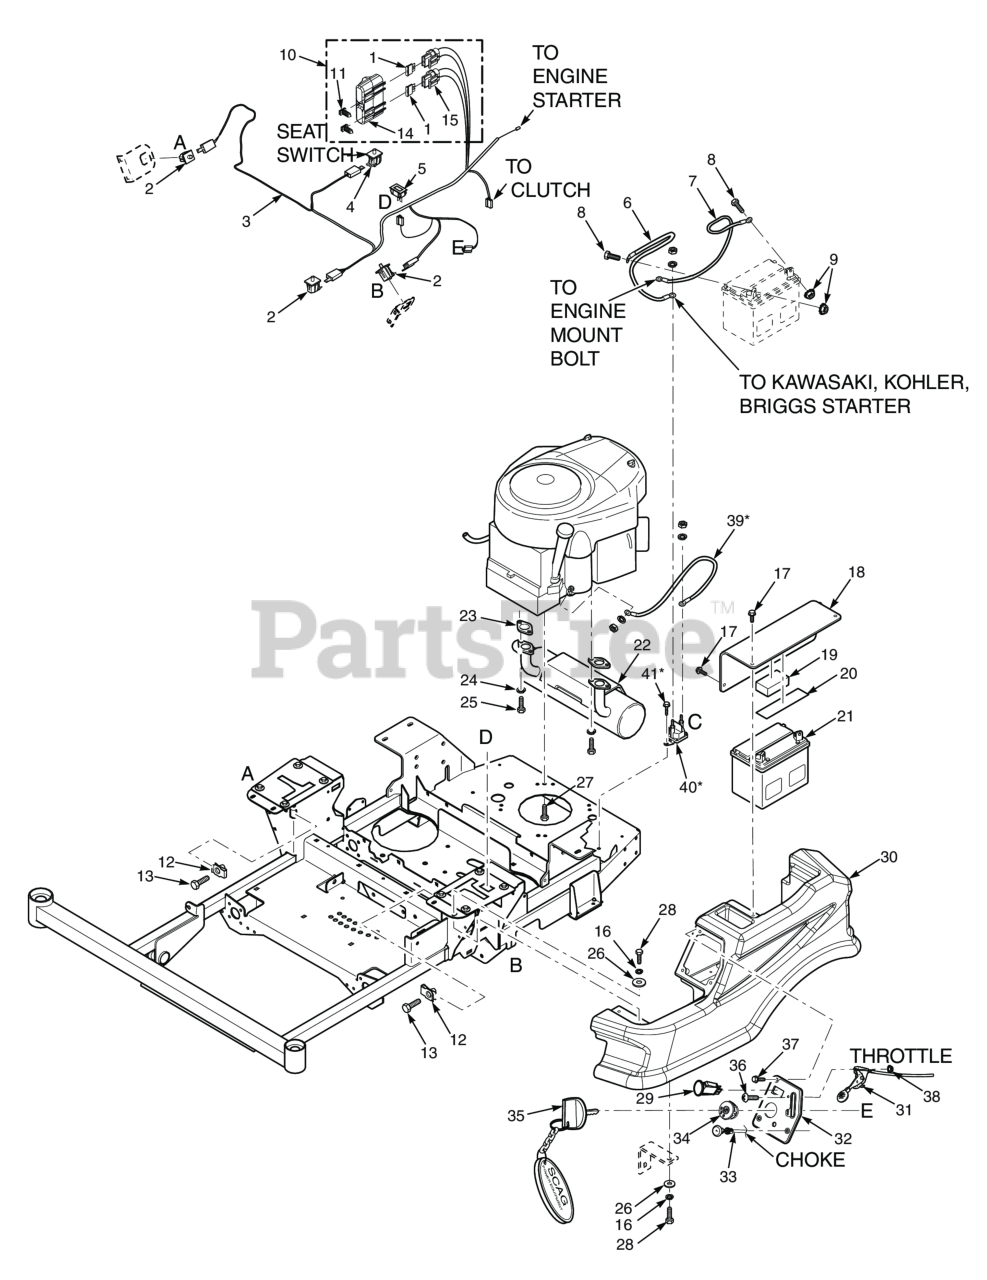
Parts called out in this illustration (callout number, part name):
1	FUSE, 20 AMP BLADE TYPE AUTOMOTIVE
2	Switch, Double Pole - Plunger
3	Wire Harness, Main
4	Switch, Double Pole - Twist
5	Hour Meter, Inductive
6	Battery Cable, 25" Red (Kawasaki)
7	Battery Cable, 27" Black (35BV & 37BV-EFI) - Briggs & Stratton
8	Bolt, Hex Head 1/4-20 x .5" Battery, (Not Available Through Scag)
9	Nut, 1/4 - 20 Hex
10	Double Fuse Assy.
11	Clip, Fuse Holder
12	U-Nut, 3/8-16 (short)
13	Bolt, Hex Head 3/8-16 x 1-1/4" with Thread Lock Patch
14	Cover, Sealed Double
15	Fuse Holder Assembly
16	Lockwasher, 5/16 (.317 x .586 x .078) Helical Spring
17	CAP SCREW, 1/4-20 X 1/2" SERRATED FLANGE HEX
18	Battery Cover (incl. items 19 & 20)
19	Pad, Battery - Rubber
20	Rubber Pad
21	Battery, 350 CCA (not available through Scag)
22	Muffler, Kawasaki FS/FX
23	Exhaust Gasket (excl. Scag Engine)
24	Lockwasher (excl. Scag Engine)
25	Bolt (excl. Scag Engine)
26	Flatwasher, 5/16-.375 x .875 x .083 (35BV & 37BV-EFI)
27	Bolt, Hex Head Self-Tap 3/8-16 x 1-1/4" (Kohler x3 - 25EFI, Kohler x4 - 29EFI)
28	BOLT, SERRATED FLANGE HEX HEAD 5/16-18 X 3/4"
29	Switch, PTO - 10 Amp
30	Console, LH - SPZ
31	Throttle Cable, Briggs & Stratton
32	INSTR PANEL W/ DECAL, SFZ
33	Choke Cable, Briggs & Stratton
34	Ignition Switch
35	Key w/Shroud Only
36	Bolt, Carriage #10-24 x 1/2"
37	Screw, Flanged, 5/16-18 x 1/2"
38	Nut, Elastic Stop #10-24
39	Battery Cable, Red 9" (Briggs & Stratton)
40	Solenoid, Sealed (Briggs & Stratton)
41	Screw, 1/4-20 x .375"
